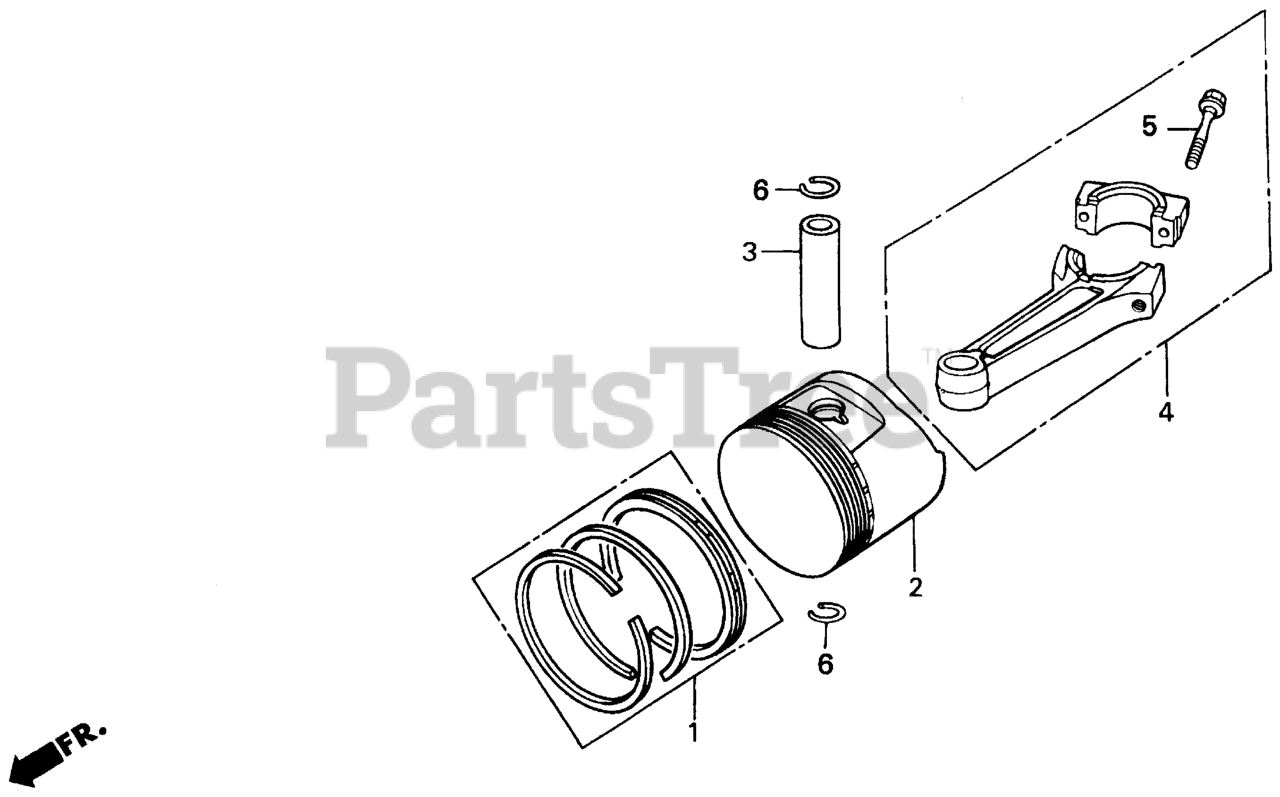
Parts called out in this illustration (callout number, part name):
1	RING SET, PISTON (STD)
1	RING SET, PISTON (OS 0.25)
1	RING SET, PISTON (OS 0.50)
1	RING SET, PISTON (0.75) (NIPPON)
2	PISTON (STD)
2	PISTON (OS 0.25)
2	PISTON (OS 0.50)
2	PISTON (OS 0.75)
3	PIN, PISTON
4	ROD ASSY., CONNECTING (US 0.25)
4	ROD ASSY., CONNECTING (STD)
5	BOLT, CONNECTING ROD
6	CLIP, PISTON PIN (20MM)
